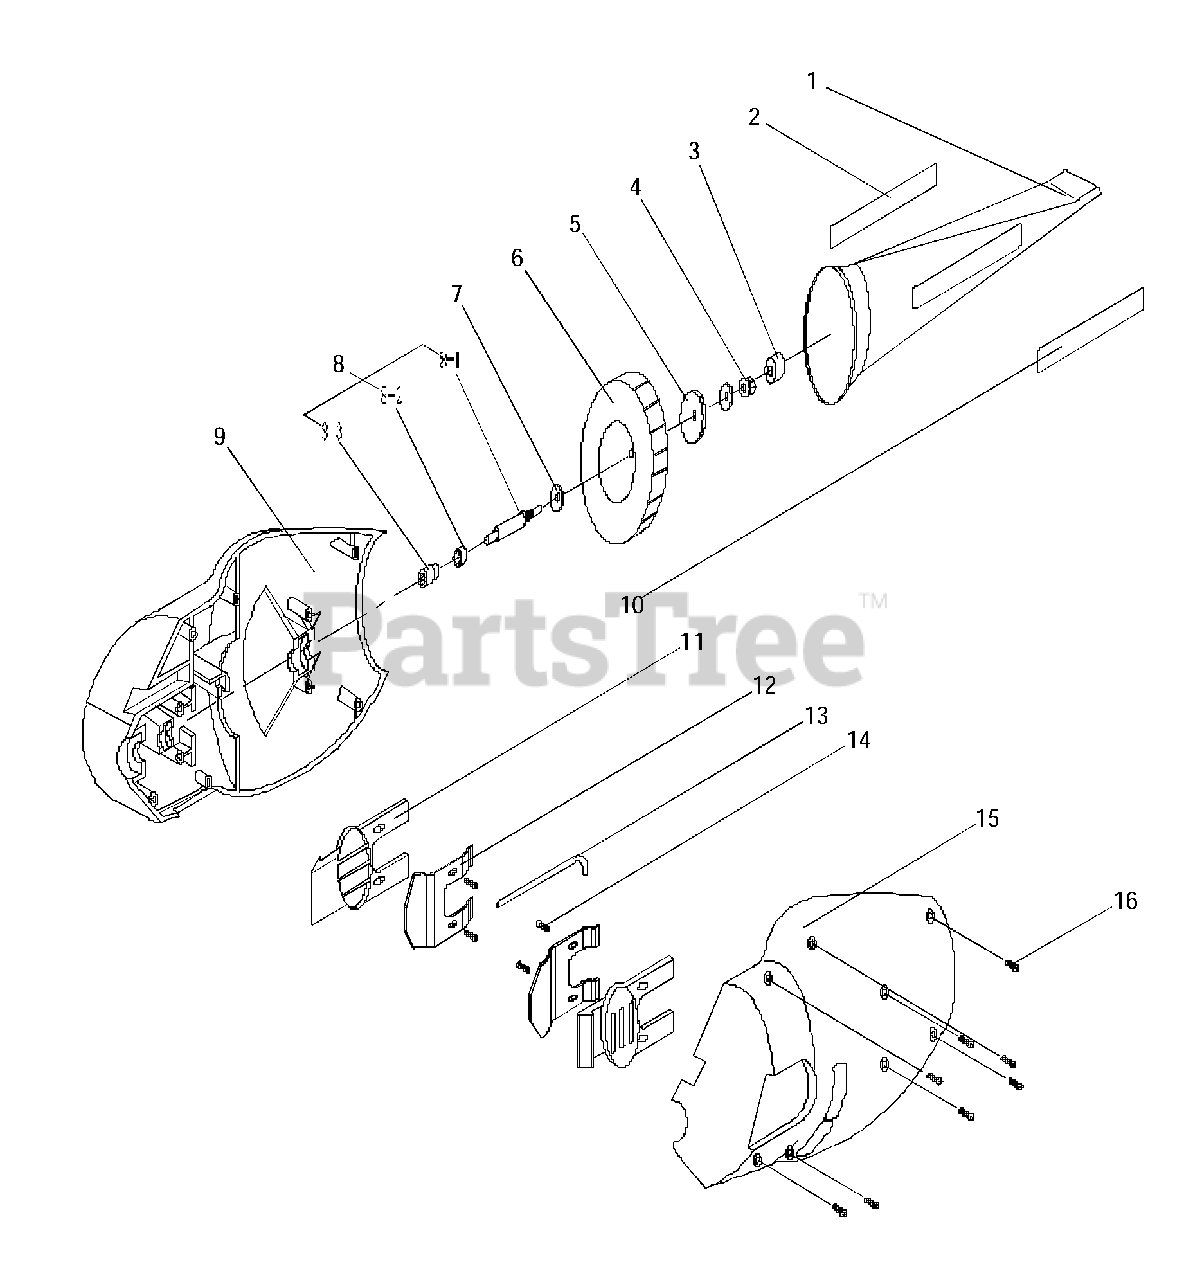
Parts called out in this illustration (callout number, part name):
8	PIVOT ASS'Y
8	JOINTING SLEEVE
9	CONNECT (L)
12	SPRING LAMINATION
15	CONNECT (R)
